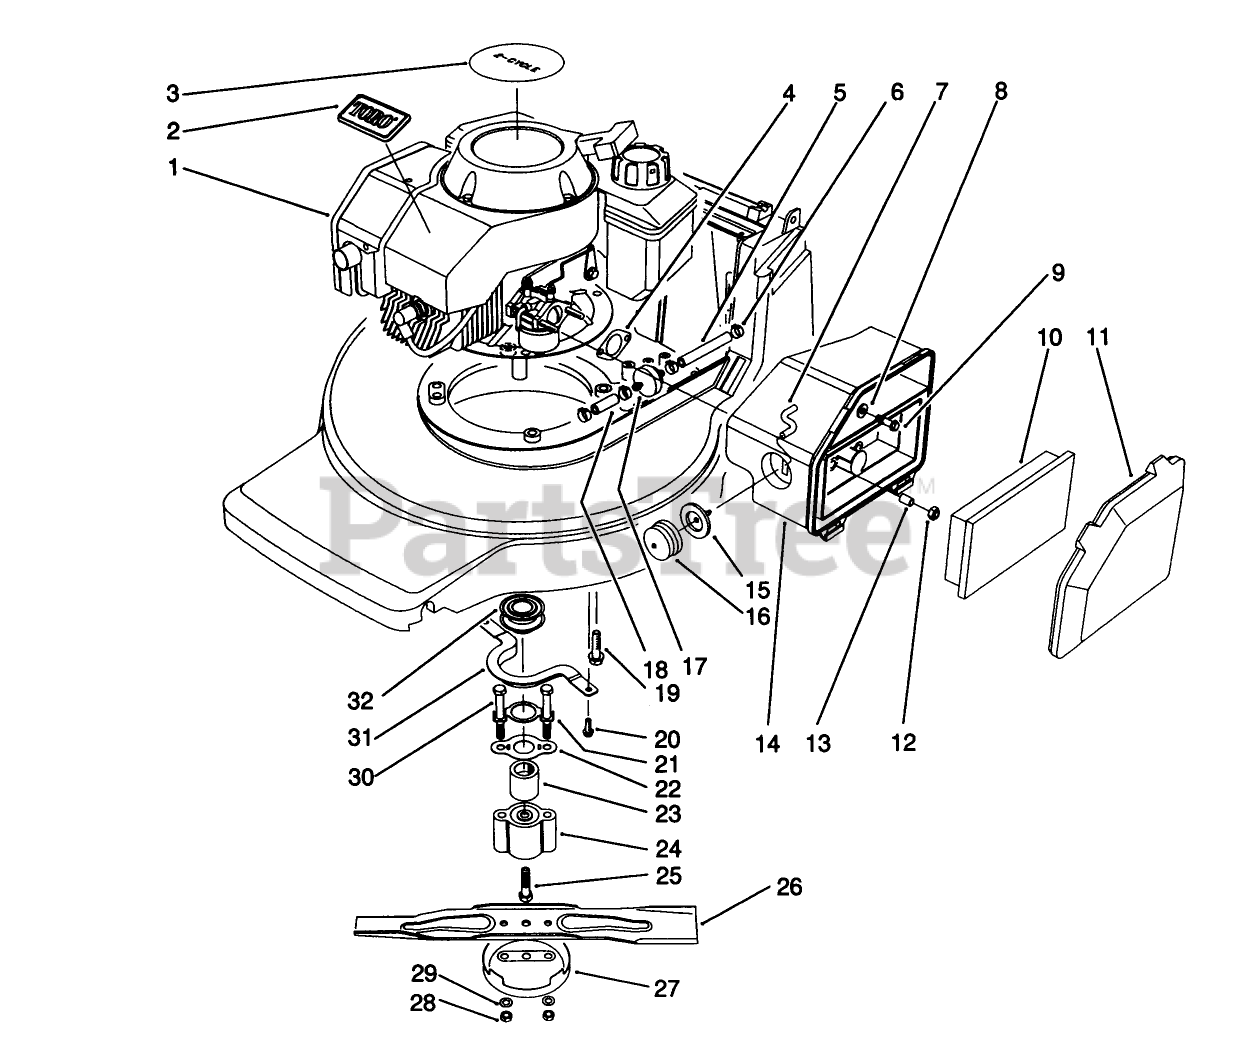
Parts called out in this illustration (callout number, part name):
1	ENGINE 121CC INT'L 2CYC
2	TORO LOGO PLT
3	DECAL- 2 CYC RECOIL
4	GASKET-AIR CLEANER
5	HOSE-FUEL
6	CLAMP-FUEL LINE
7	HOSE-PRIMER
8	WASHER-FLAT
9	SCREW-HH
10	ELEMENT-AIR CLEANER
11	COVER-AIR CLEANER
13	SPACER
14	BODY-AIR CLEANER
15	BODY-PRIMER
16	BULB-PRIMER
17	FILTER-FUEL
18	HOSE-FUEL
19	Bolt-Engine
20	SCREW-HWH
21	BLADE RETAINER BRKT
22	SPRING FRICTION
24	RETAINER
25	SCREW - CRANKSHAFT
26	Blade-48cm
27	Anti Scalp Cup
28	Nut
29	WASHER
30	SCREW - BLADE
31	Guide-Belt
32	PULLEY-DRIVE, ZONE START
